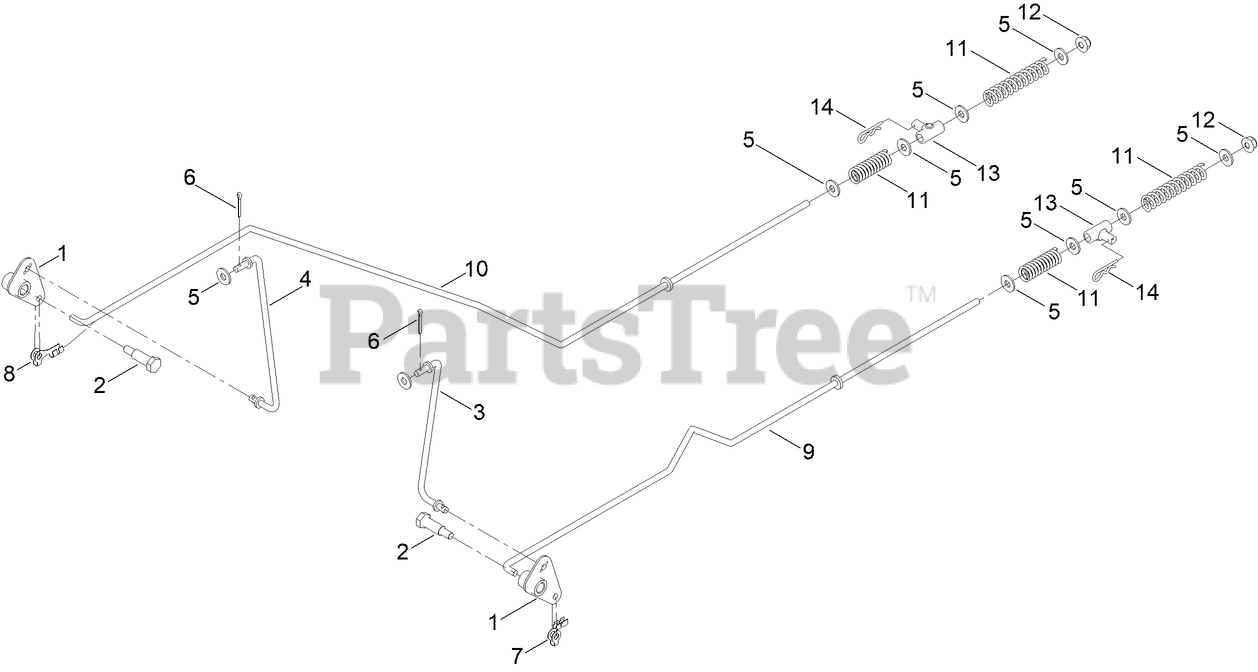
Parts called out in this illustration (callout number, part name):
1	BELLCRANK
2	BOLT - SHOULDER
3	LINK-BRAKE, LH
4	LINK-BRAKE, RH
5	WASHER
6	PIN-COTTER
7	CLIP, ROD, LH, 7L, 1/4IN
8	CLIP, ROD, RH, 7R, 1/4IN
9	ROD-BRAKE LH
10	ROD-BRAKE, RH
11	SPRING-COMPRESSION
12	NUT-FLANGE, NI
13	MOUNT-PIVOT
14	PIN-HAIR
